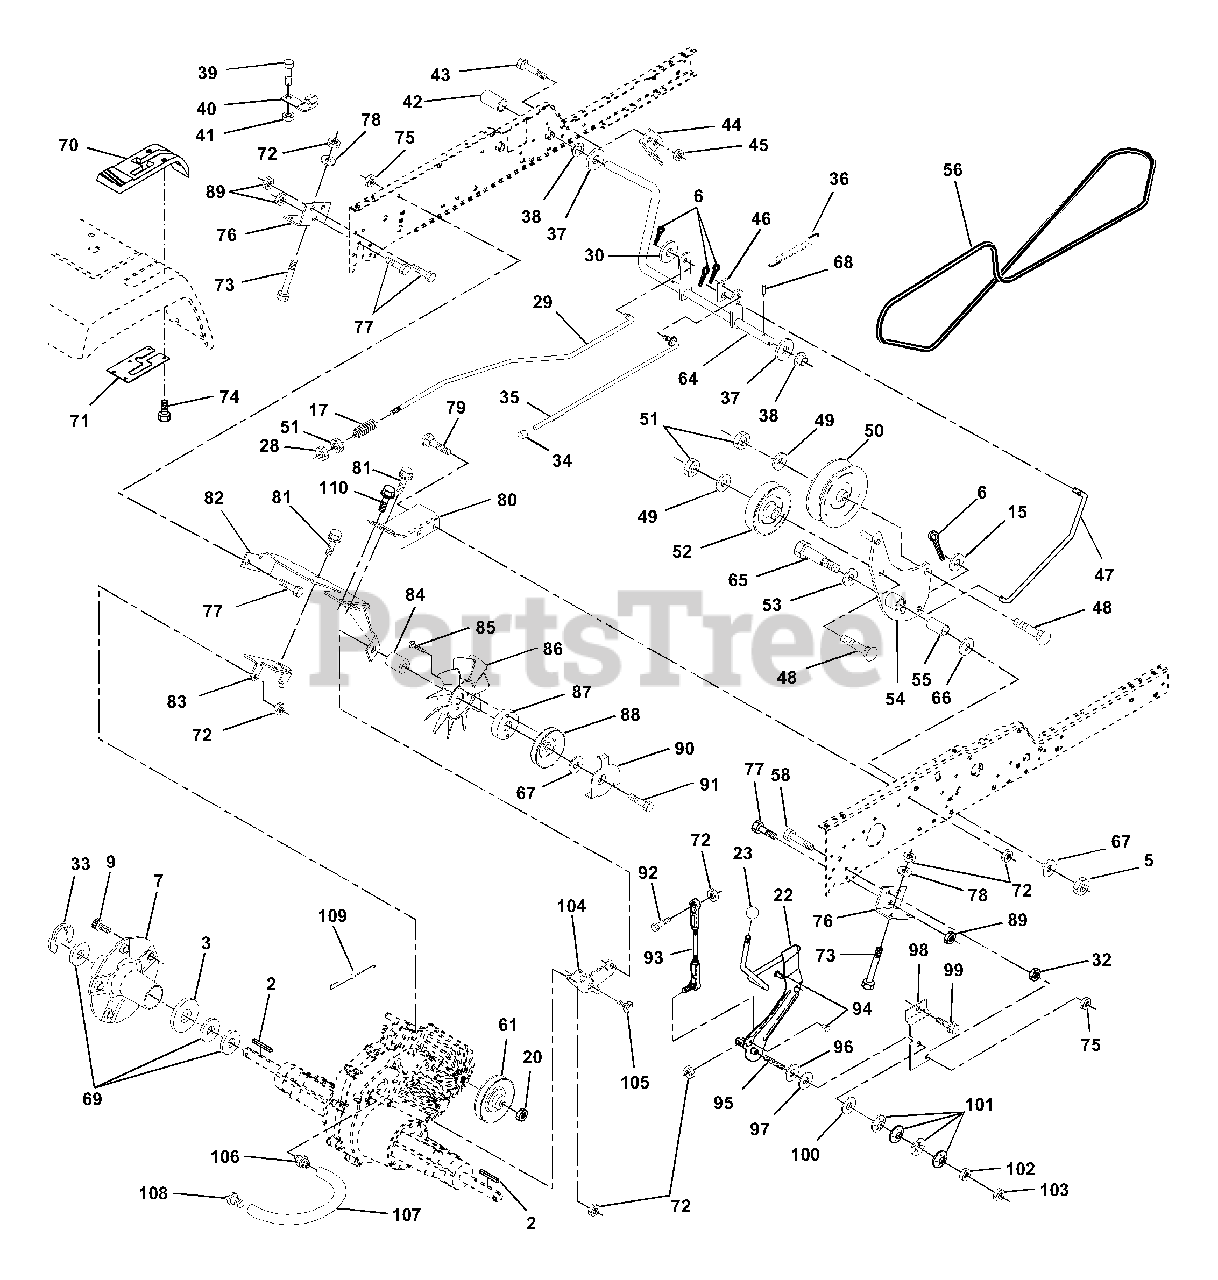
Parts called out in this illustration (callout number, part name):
2	Key 1/4 x 2.5
3	Washer Thrust Axle Harden
5	Nut Crownlock 3/8-16
6	Pin Cotter 1/8 x 3/4
7	Wheel Hub Asm.
15	Washer 13/32 x 13/16 x 16 Ga.
17	Spring Rod Brake
20	Nut Hex Jam Toplock 1/2-20
22	Shaft Arm Asm
28	Nut, Hex Jam 3/8-16
30	Washer 13/32 x 1 x 16 Ga
32	Nut Hex 7/16-14
34	Cap Plunger
35	Rod Parking Brake
36	Spring Extension
37	Washer 25/32 x 1-1/4 x 16 Ga.
39	Screw Fin #10-24 x 1
40	Actuator Interlock Switch
41	Nut Lock #10-24
42	Cover Pedal
43	Bolt Hex Head 1/4-20 x 3/4
44	Bracket Interlock
45	Nut Lock W/Insert 1/4-20
46	Retainer Spring
47	Clutch Rod
48	Bolt Carriage 3/8-16 x 1-3/4 Gr. 5
49	Washer 13/32 x 7/8 x 13 Ga
50	Pulley Idler Flat
51	Nut Crownlock 3/8-16 UNC
52	Pulley Idler Grooved
53	Washer Hartdened
54	Clutch Arm Asm
55	Bearing, Idler
58	Bolt Fin Hex 7/16-14 x 1-1/2
61	Pullery Transaxle
64	Shaft Asm Brake Parking Clutch
65	Bolt Shoulder
66	Washer Hardened
67	Washer 13/32 x 13/16 x 12 Ga
70	Console Hydro Fender
71	Plate Console Shift
72	Nut Crownlock 5/16-18
73	Bolt Fin Hex 5/16-18 x 3
74	Screw, Hex Wsh Hi-Lo 1/4-1/2
75	Nut Lock Hex 7/16
76	Bracket Transaxle
77	Bolt Fin Hex 7/16-14 x 1
78	Washer 11/32 x 3/4 x 12 Ga.
79	Bolt Carriage 5/16-18 x 5/8
80	Bracket Torque RH
81	Screw Thdrol 3/8-16 x 3/4
82	Bracket Mount Torque/Fan
83	Strap Torque Mid
85	Screw #10-24 x 1-1/4
86	Fan 7" Hydro
87	Adapter Fan
88	Pulley Idler
89	Nut, Crownlock 7/16-14
90	Keeper Belt
91	Screw Thdrol 3/8-16 x 2-3/4
92	Bolt Fin Hex 5/16-18 x 1.75
93	Link Shift Asm
94	Fastner Christmas Tree
95	Screw Set 5/16-18 x 1.75
96	Washer Nickel Plated
97	Bearing Trust
98	Bracket Shift
99	Screw Thdrol 3/8-16 x 1-1/2
100	Washer Compression
101	Washer Bellville
102	Nut Hex Nylok
103	Nut Hex Jam 5/16-18
104	Bracket Idler
105	Screw Tap 1/4-20 x 1/2
106	Fitting Vent Hose
109	Spring Return Brake
110	Screw, Hinge
